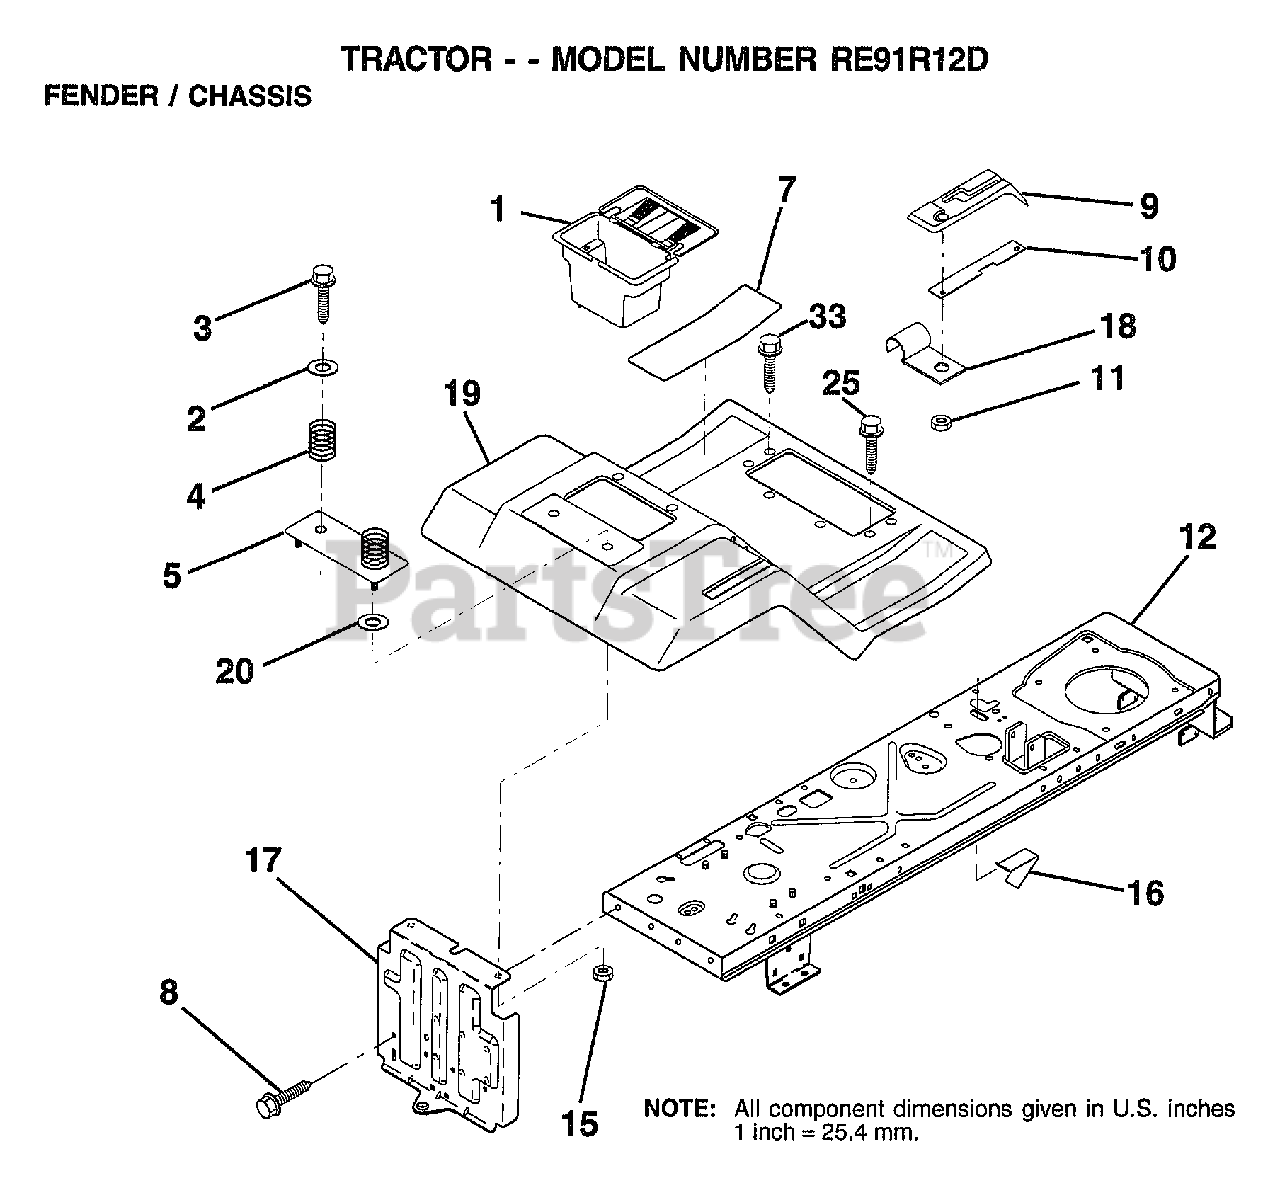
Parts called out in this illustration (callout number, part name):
1	"CASE,BATTERY.MECH"
2	WASHER
3	SCREW
4	SPRING COMPRESSIO
5	BTRY FENDER PLATE
7	PAD FOOTREST
8	SCREW
9	CONSOLE.SHT.4SP.
10	PLATE LOCK SHIFT
11	NUT
12	CHASSIS.WELD.ASM.
15	NUT HXKEP 1/4X20
17	DRAWBAR ASM LR
18	"CLIP,INSULATOR"
19	FENDER/FOOT MS505
25	SCREW TAPPING
33	SCREW
